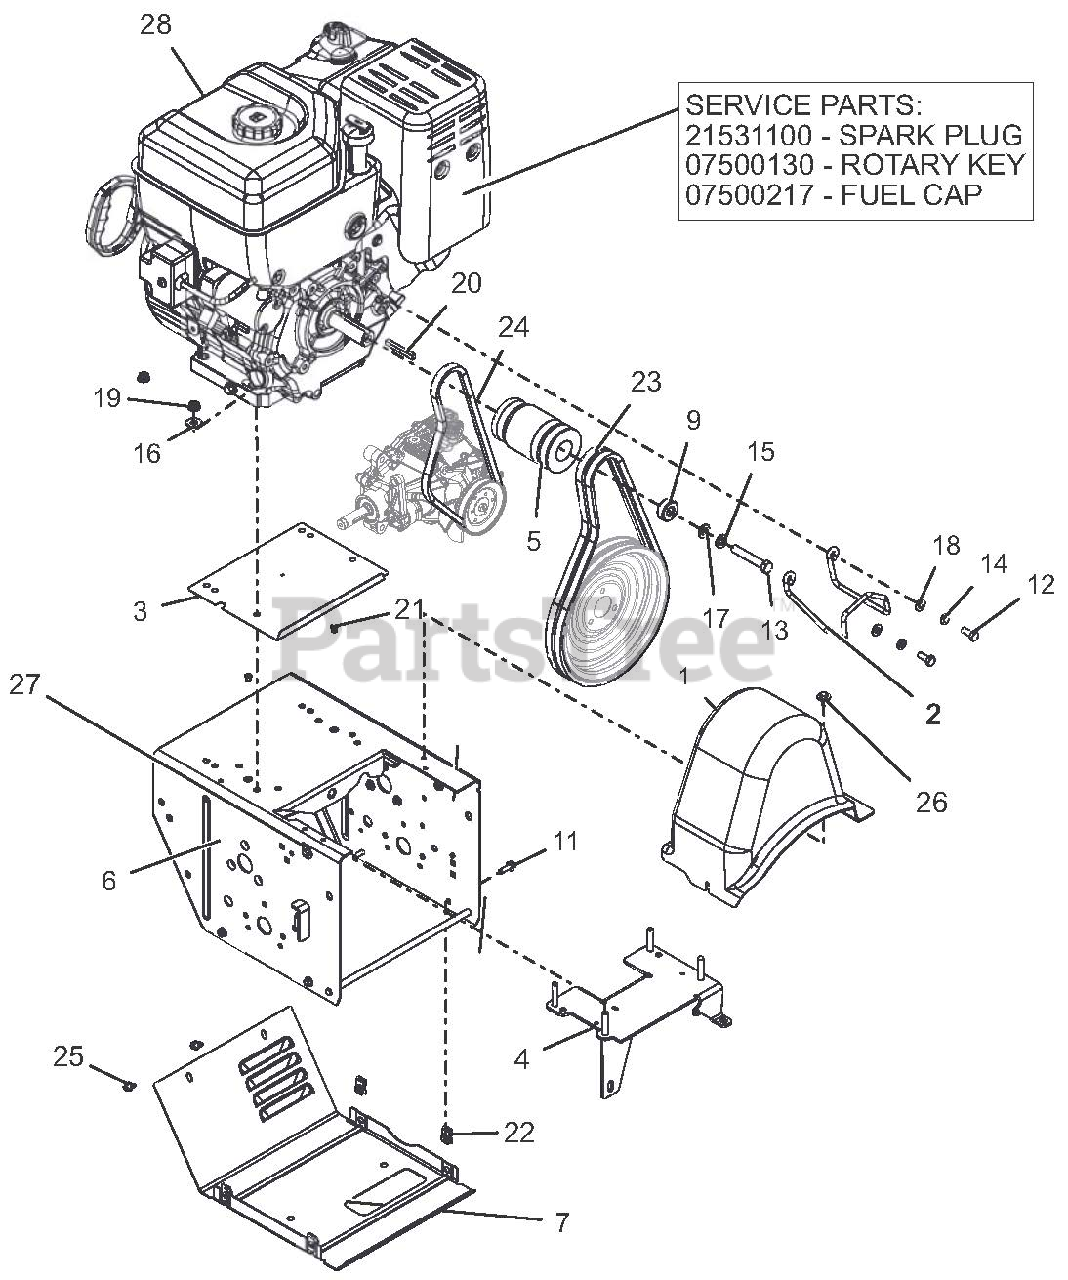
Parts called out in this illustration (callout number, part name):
1	COVER, BELT-LARGE PRO
2	FINGER, BELT
3	BAFFLE,ENGINE-PRO SERIES
4	BRACKET, HYDROSTATIC TRANS XLG
5	SHEAVE, COMBO HYDRO WHEEL 4L
6	PRO HYDRO FRAME, MAIN
7	COVER, BOTTOM - VENTILATED
9	BSHG-SPACER .47X1.25X.50
11	BLT-HEX .25-20X.75 HWH YZ GR5
12	BLT-HEX .31-24X.75 YWZC GR5
13	BLT-HEX .44-20X2.50 GR5 YWZC
14	WSHR-LK .312X.097 HVY YWZC
15	@WSHR-LK .44X.109 REG YWZC
16	@WSHR-FL-STL.38X.875X.083 YWZC
17	@WSHR-FL-STL.406X.812X.065 YWZ
18	@WSHR-FL-STL.344X.688X.065YWZC
19	@NUT-LK-CTR-FLG .31-18 YZ GR F
20	KEY .25X.25X2.25
21	RVT-POP .187 YZ
22	NUT-RTNR .25-20X.56
23	V-BELT, HA-RAW EDGE (SET)
24	V-BELT, 4L-WRAPPED
25	SCR-TAP .25-20X.50 HWH TR YWZ
26	SCR-TAP .25-20X.50 LGHWH TR YZ
27	SCR-TAP .25-20X.5 CAPTIVE
28	ENGINE, BRIGGS PF 2100, 12V
28	PLUG, SPARK 20HP B&S VANGUARD
28	KEY, IGNITION ROTARY B&S
28	CAP, FUEL - BRIGGS & STRATTON
